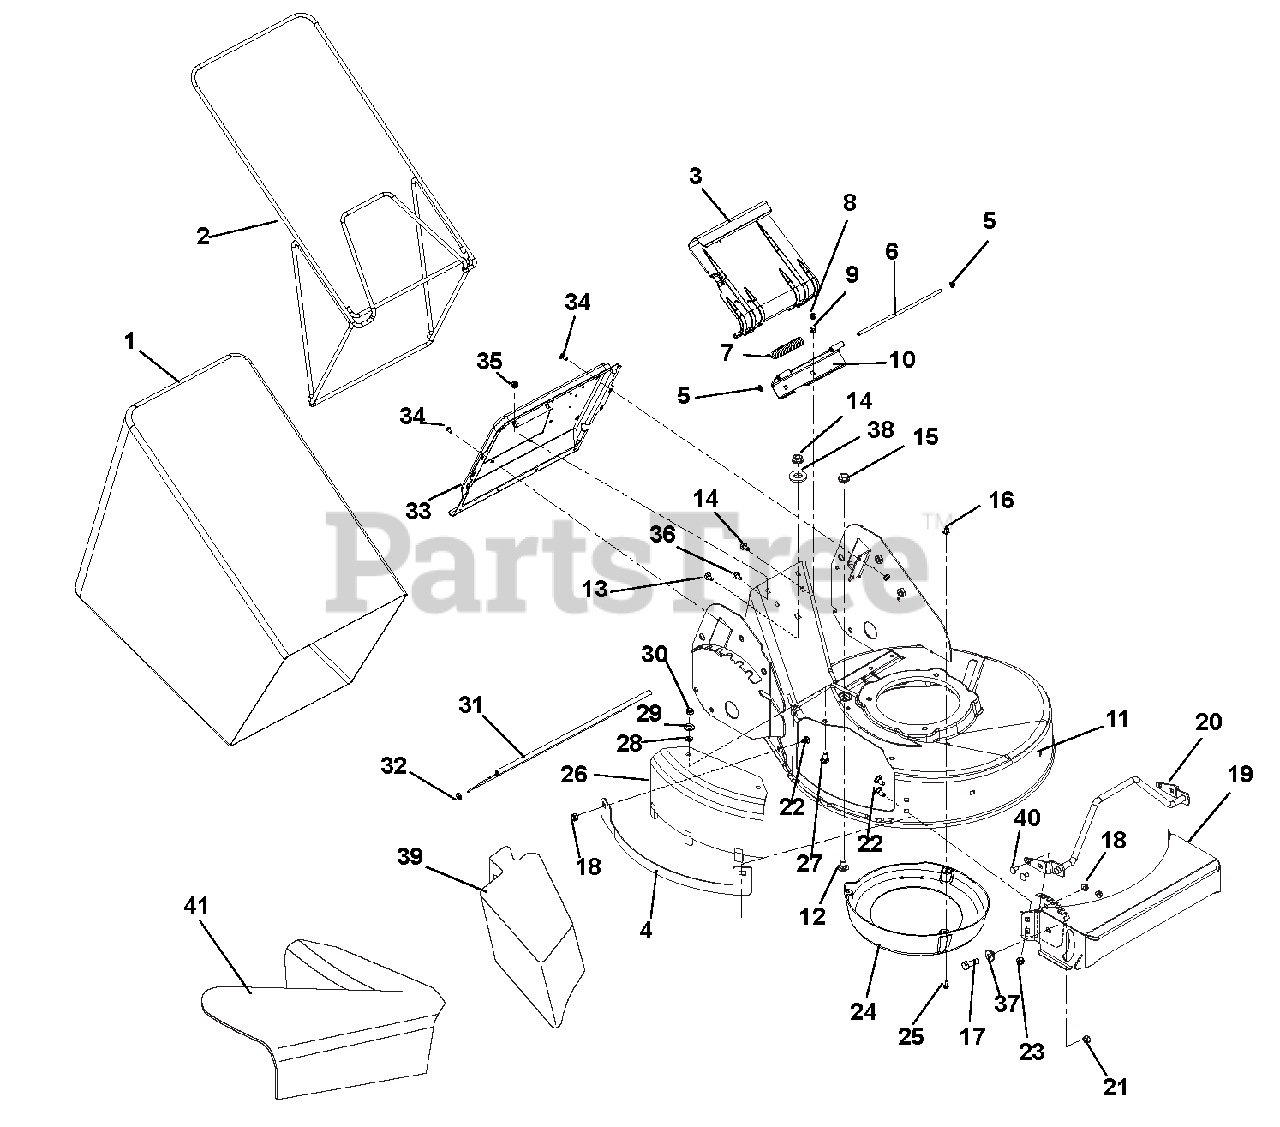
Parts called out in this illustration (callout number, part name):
1	BAG, CONSUMER BLACK 15 OZ/YD2
2	FRAME, WBLM BAGGER
3	CATCHER PLATE DOOR
4	BRKT, DISHCARGE GUARD
5	PUSH NUT, .25
6	DOOR PIN
7	SG-TORS .120X.68X3.09
8	@NUT-HEX .25-20 YWZC
9	WSHR-LK .250X.077 HVY YWZC
10	HINGE BASE
11	KIT, PRO21 DECK WITH DECALS
12	@BLT-HEX .25-20X.50 GR5 YWZC
13	@BLT-HEX .38-16X.50 GR5 YWZC
14	@BLT-RDHDSQNK .25-20X.75 G5YZ
15	@NUT-SPNLK-FLG .25-20 YWZC
16	PLASTIC GROMMET
17	@BLT-HEX .31-18X1.00 GR5 YWZC
18	@NUT-LK-TOP-FLG .31-18 YWZC
19	WLDMT, COMMERCIAL 21 BUMPER
20	WLDMT, VALVE COVER GUARD
21	@NUT-LK-CTR .31-18 YWZC
22	@BLT-RDHDSQNK .31-18X.75 G5YZ
23	@NUT-SPNLK-FLG .312-18 YWZC
24	CENTER BAFFLE
25	SCR-TAP 10-16X.62 SLPH AB YWZC
26	COVER, SIDE DISCHARGE
27	BLT-RDHDSQSHK.31-18X.75 GR2 YW
28	NUT-PUSH .312
29	@WSHR-FL-STL.406X.812X.065 YWZ
30	@NUT-LK-NYL .312-18 YWZC
31	TRAILING SHIELD
32	RETAINER, .38 PUSH-ON
33	CATCHER PLATE
34	SCR-TAP 1/4-20X3/4 LPAN TL BZ
35	@NUT-SPNLK-FLG .25-20 YWZC
36	@BLT-RDHDSQNK .25-20X.50 G5YZ
37	BSHG-FLG .32X.500X.344X.880
38	WSHR-FL-STL.511X1.441X.125 YWZ
39	MULCH MASTER MULCHER ACCESSORY
40	@BLT-RHDSSQNK .31-18X.62 G5YZ
41	SIDE DISCHARGE ASSEMBLY
